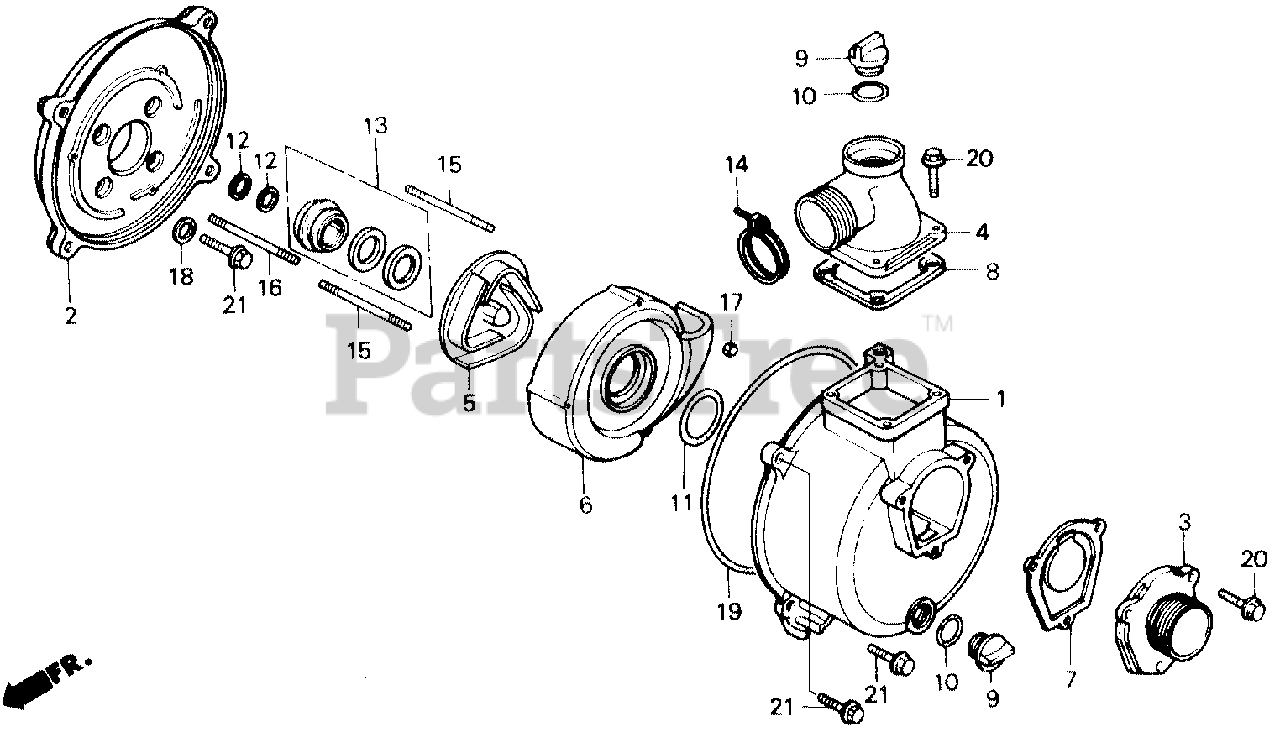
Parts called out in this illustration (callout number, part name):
1	CASING (HONDA) (NOT AVAILABLE)
2	COVER, CASING
3	PIPE, INLET
4	OUTLET (NPTF)
6	CASE, VOLUTE
7	VALVE, IN.
8	GASKET, OUTLET
9	CAP, FILLER
10	RING, SEAL (B)
11	O-RING (49X5.7) (NOK)
12	SHIM, ADJUSTER
13	SEAL ASSY., MECHANICAL WATER
14	BAND, HOSE
15	BOLT, STUD (6X50)
16	BOLT, STUD (6X50)
17	NUT, CAP (6MM)
18	WASHER, SEALING (8MM)
19	O-RING (217.5X3.5) (ARAI)
20	BOLT, FLANGE (8X25)
21	BOLT, FLANGE (8X28)
